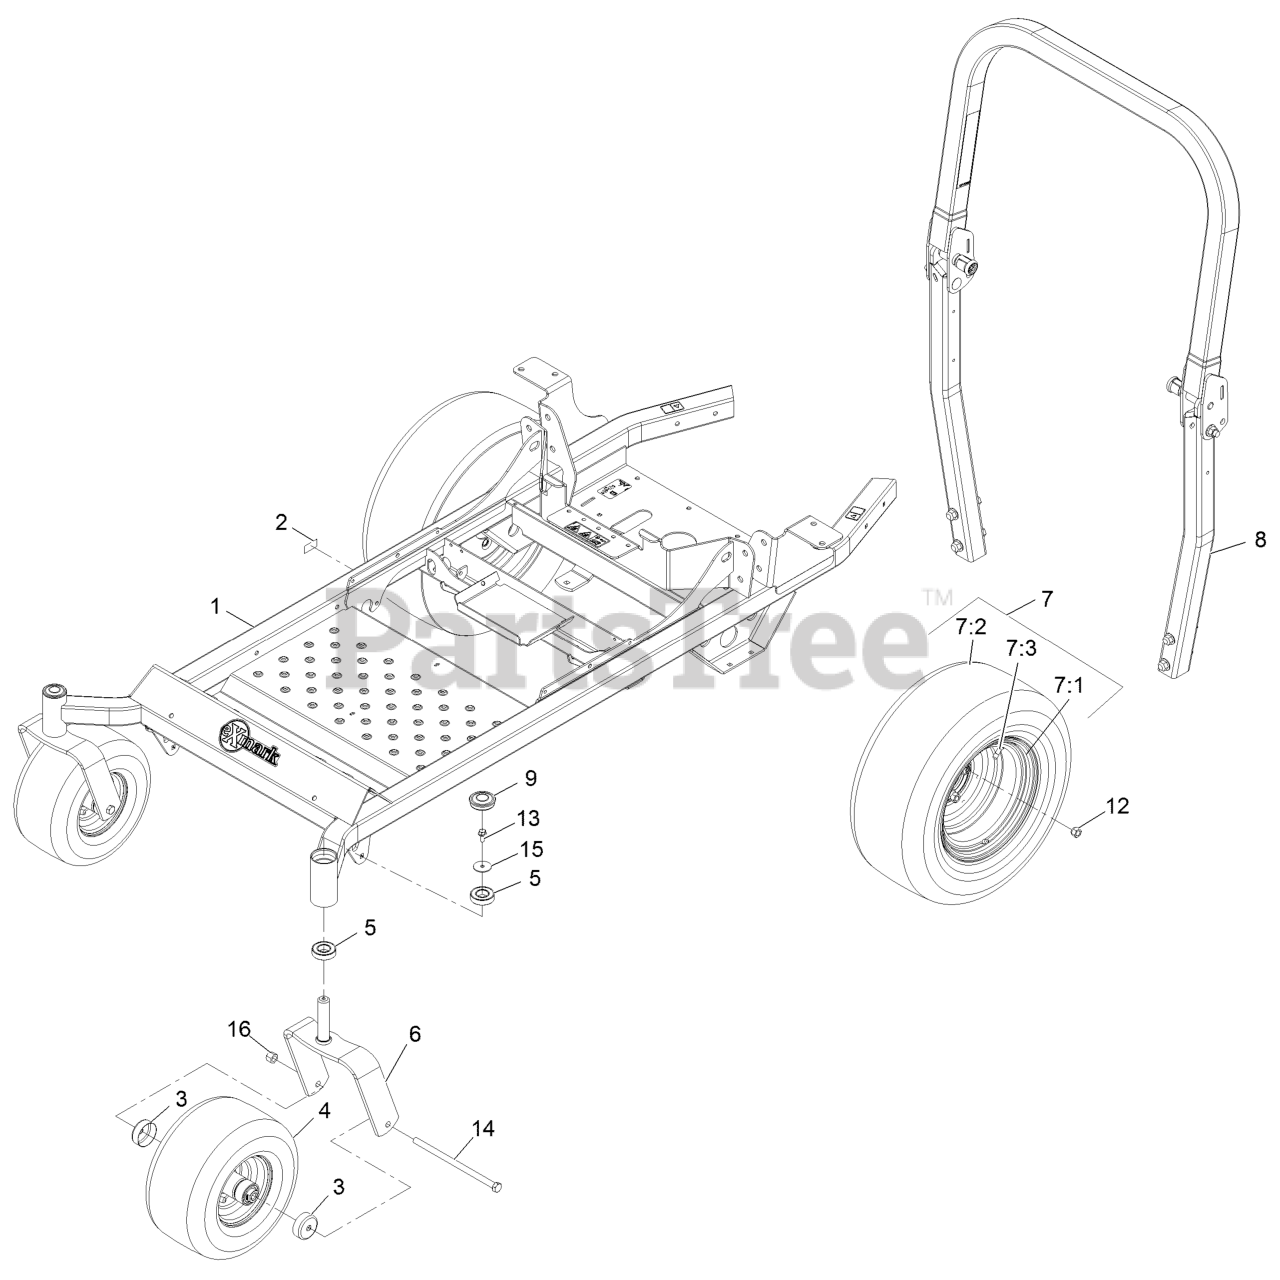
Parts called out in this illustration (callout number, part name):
1	FRAME-PIONEER 60RD
2	Decal-Patent Ttco.Com
3	GUARD-SEAL
4	CASTER WHEEL ASM
5	BEARING-BALL
6	CASTER FORK WIDE
7	WHEEL AND TIRE ASM
7:1	WHEEL
7:2	TIRE
7:3	Stem-Valve
8	ASM-ROPS PIONEER
9	CAP-GREASE
12	NUT-LUG
13	SCREW-HHF
14	SCREW-HH
15	WASHER-FLAT
16	NUT-LOCK, NI
